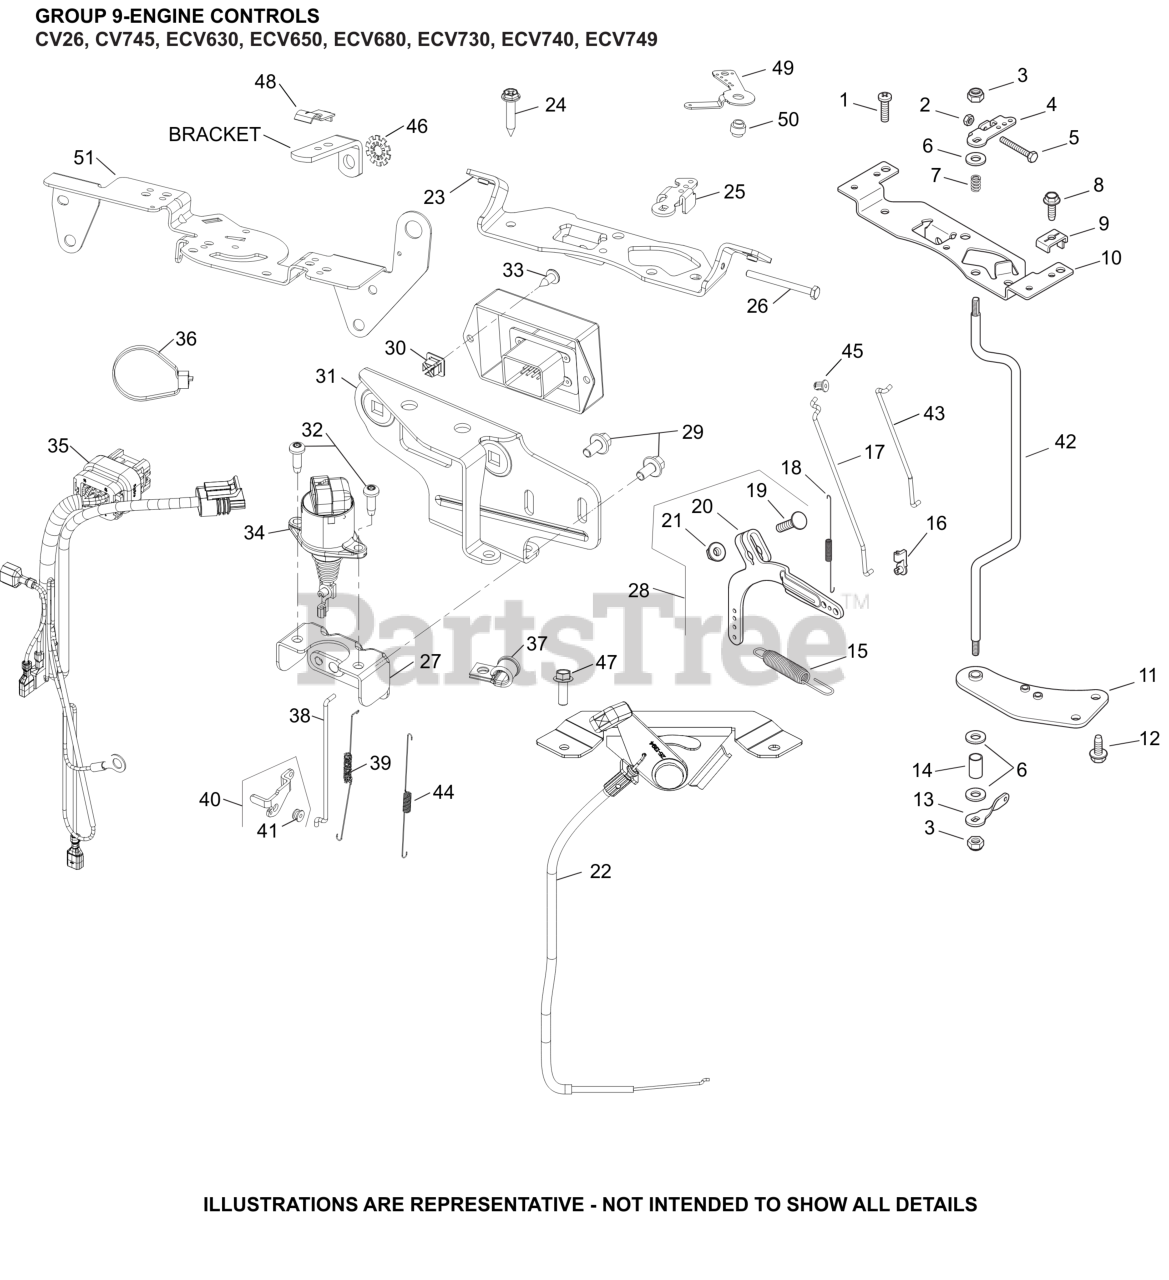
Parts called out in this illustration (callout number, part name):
3	NUT, LOCK M6X1.0
6	WASHER, FLAT 1/4"
7	SPRING, THROTTLE SHAFT
9	CLAMP, CABLE
11	BRACKET, THROTTLE SHAFT
12	SCREW, THREAD FORMING
13	LEVER, THROTTLE CONTROL
15	SPRING, GOVERNOR (BLACK)
16	BUSHING, THROTTLE LINKAGE
17	LINKAGE, THROTTLE
18	SPRING, LINKAGE
19	BOLT, RD HD SQ NECK M6X1.0X25
20	LEVER, GOVERNOR - (#2409069S)
21	NUT, FLG M6X1.0
23	BRACKET, CONTROL
25	LEVER, THROTTLE CONTROL
26	SCREW, HEX HEAD
28	LEVER, GOVERNOR ASSEMBLY
42	THROTTLE CONTROL SHAFT
52	SCREW, THREAD FORMING
53	SCREW, HI-LOW
